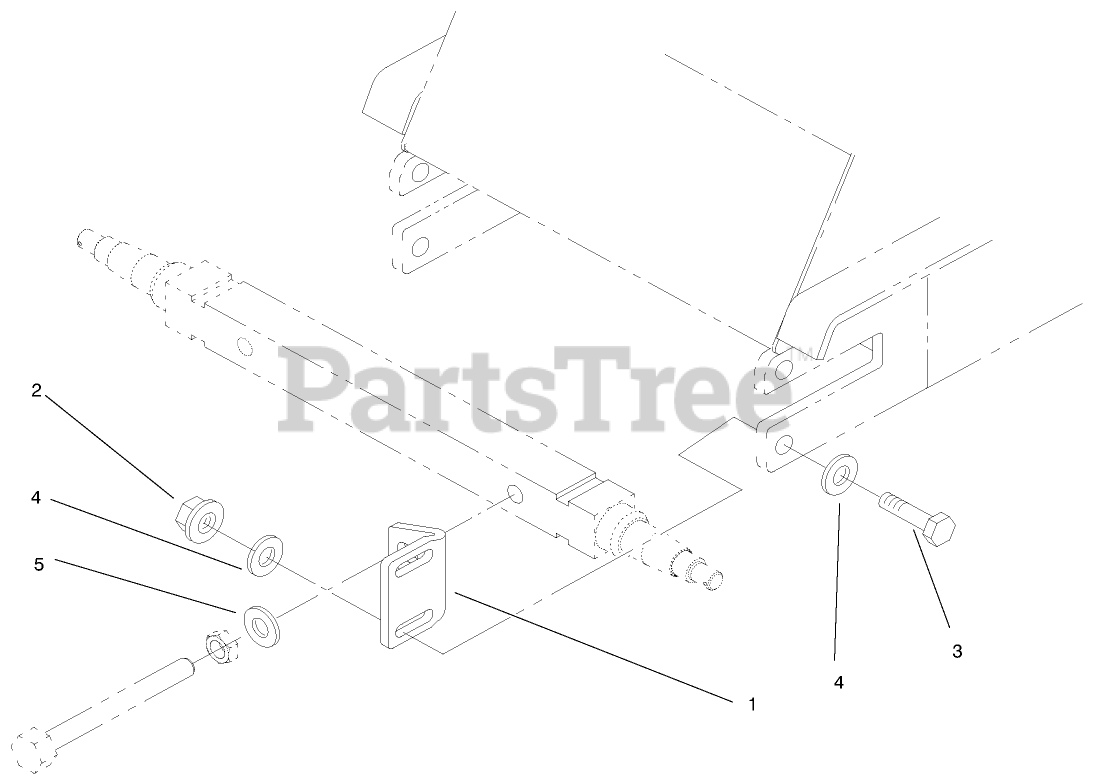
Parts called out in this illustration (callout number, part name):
1	BRACKET-AXLE
2	NUT-LOCK
3	SCREW-HH
4	WASHER-FLAT
5	WASHER-FLAT
